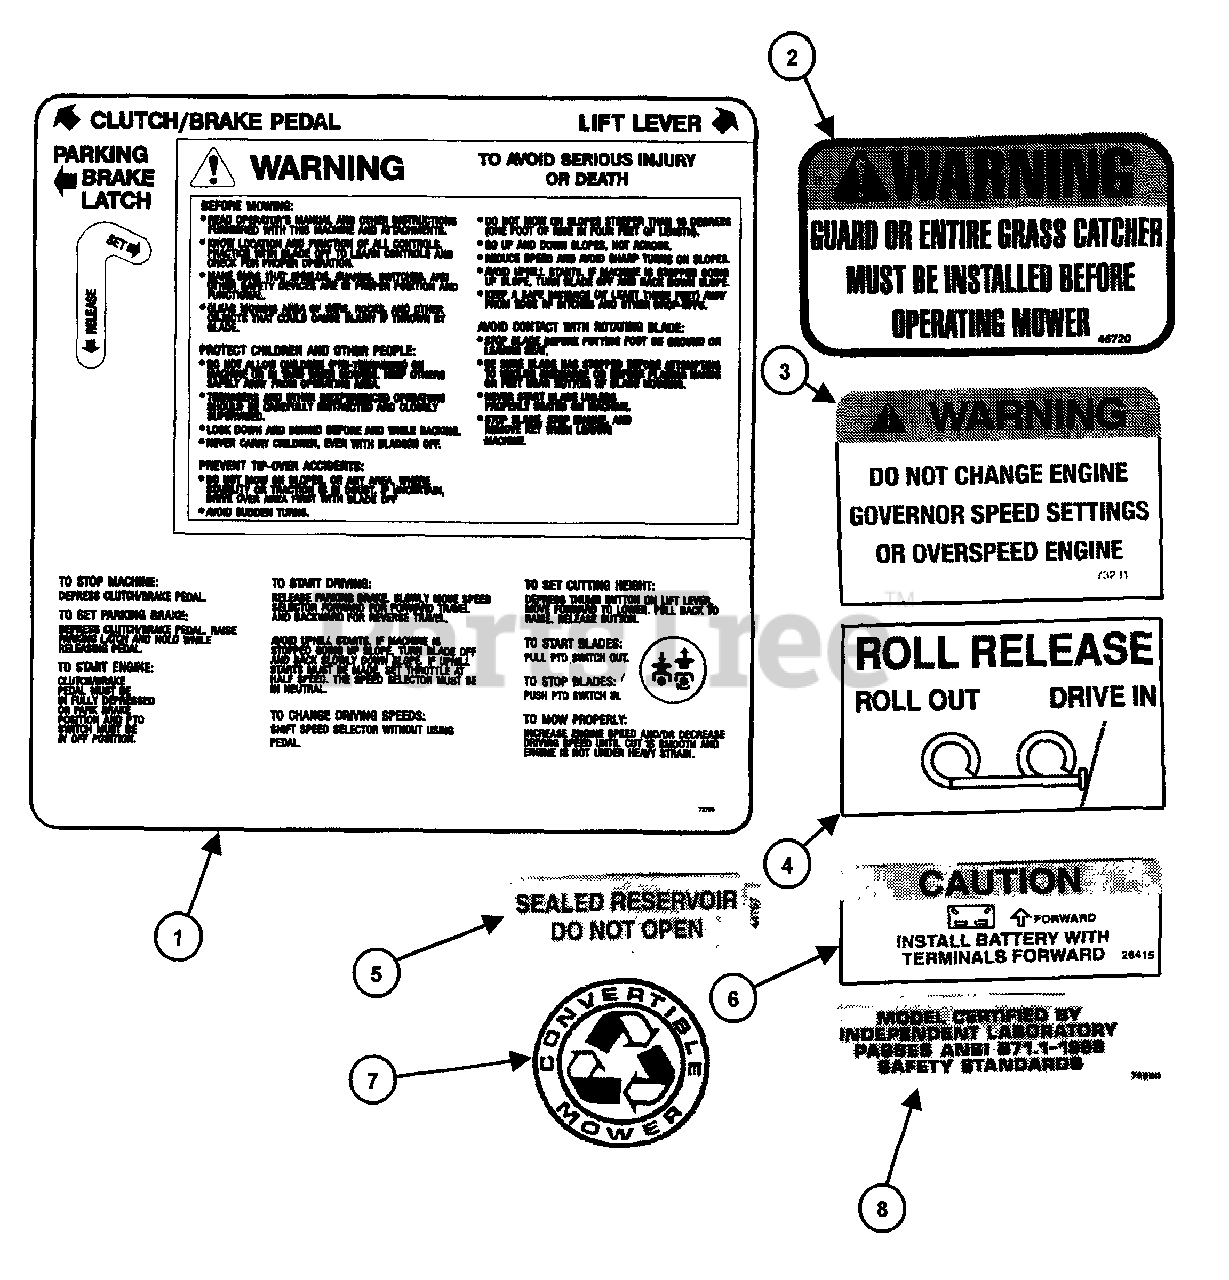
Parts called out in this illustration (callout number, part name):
1	DECAL, Instruction Frame Top
2	DECAL, Chute/Deflector
3	DECAL, Warning Speed Setting
4	DECAL, Roll Release
5	DECAL, Hydro Reservoir
6	DECAL, Caution Battery Location
7	LOGO, Medallion
8	DECAL, Certification, B71.1-1998
